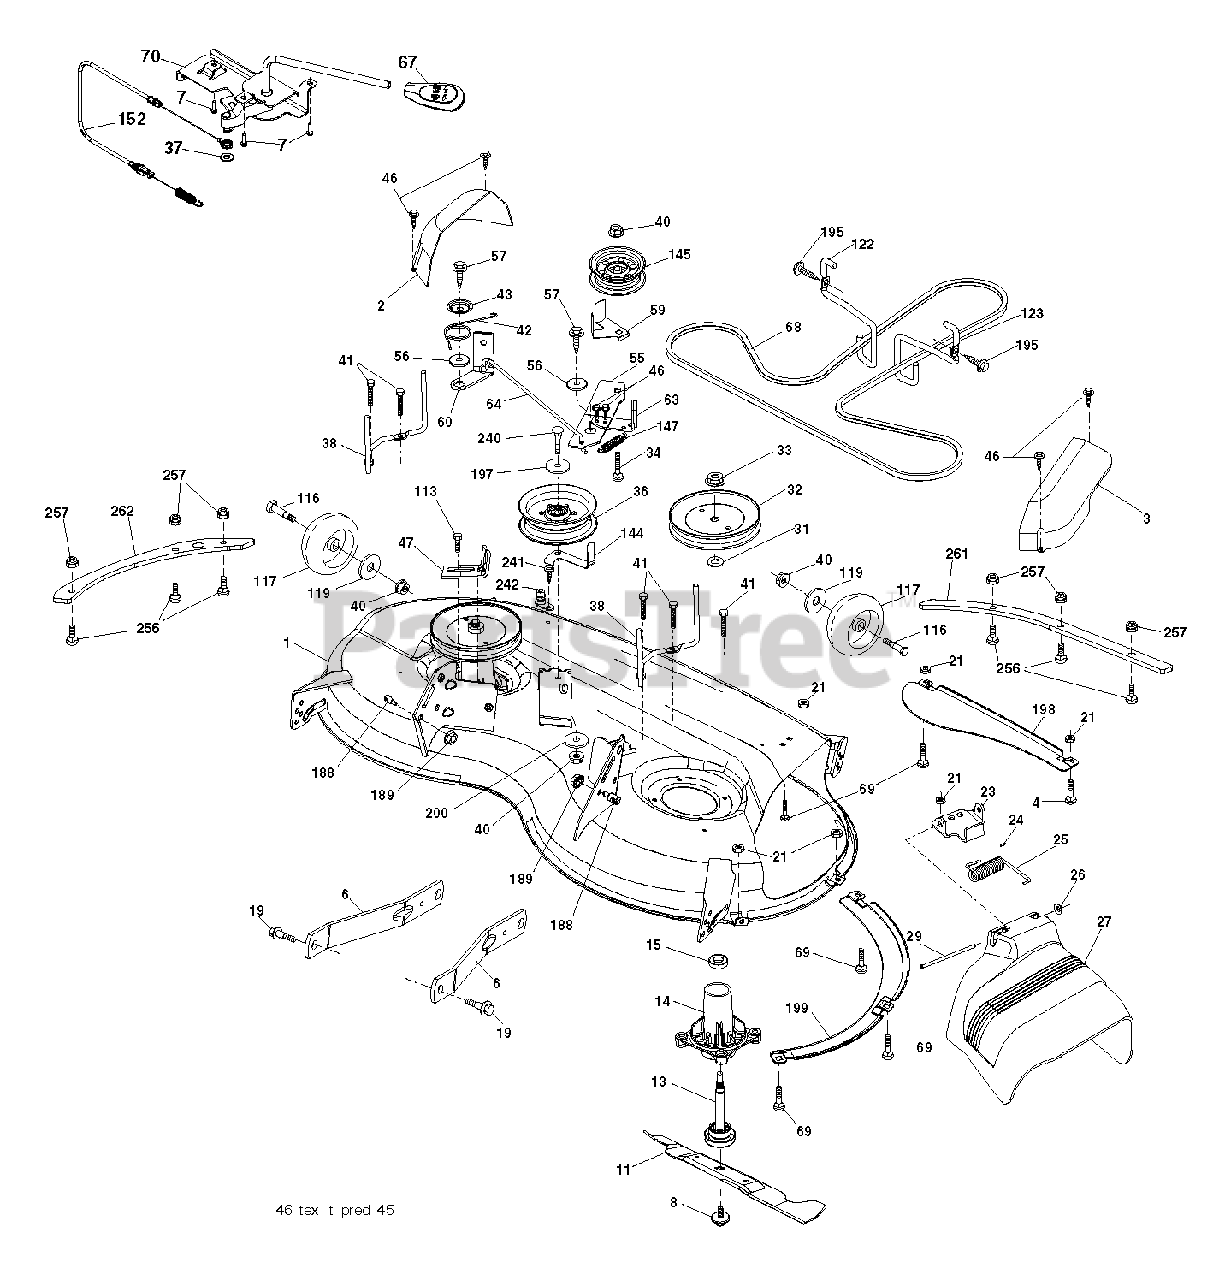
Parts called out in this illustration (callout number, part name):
1	DECK SVC 46"583900906X421
2	COVER.MANDREL.LH.46"
3	COVER.MANDREL.RH.46"
4	BOLT
6	ARM.SUSPENSION.MOWER.R
7	SCREW.#10 X 0.750.BOS (2 2)
8	BOLT.WASHER.ASM.7/16-2
11	BLADE.MOWER.46".HI.LIFT
13	SHAFT.ASM.MDRL.N/GREASE.38
14	HOUSING.MANDREL.4PT.
19	BOLT.SHOULDER
21	LOCKNUT
23	BRKT.DEFLECTOR.38"2005+
24	CAP-SLEEVE LT
25	SPRING.TORSION.DEFLECT
26	NUT PUSH M
27	SHIELD.DEFLECTOR.MOWER.46"BLAC
29	ROD.HINGE
31	WASHER.SPACER.MANDREL
32	PULLEY.MANDREL.5.438.PD
33	NUT.FLANGE.LOCK.TOP
34	BOLT.3/8-16X1.50
36	PULLEY.IDLER.2006
38	KEEPER.BELT.MANDREL.PULLEY
40	NUT LOCK FLG 3/8-16 UNC
41	Hex Washer Head Bolt, .313-18 X 1.19
42	SPRING.TORSION.BRAKE
43	SRPING.TORSION.RETAINE
46	SCREW.1/4-20X5/8
47	BRKT.CLUTCH.CABLE
55	IDLER.ARM
56	SPACER.RETAINER
57	SCREW 3/8-16X1
59	GUARD, BELT
60	ARM BRAKE MOWER RH 38"
64	LINKAGE BRAKE
67	HANDLE.CLUTCH.CABLE.LT
68	V-BELT
69	BOLT
70	CLUTCH.ASM.MANUAL.YT.PREDATORQ
113	BOLT.5/16HEX.WHS.HD
116	BOLT M
117	WHEEL.GAGE.HALF.SPOKED
119	WASHER
122	KEEPER BELT ENGINE LH
123	KEEPER BELT RH
144	KEEPER.BELT.MOWER
145	PULLEY.IDLER.48"PRIMARY
147	SPRING RETURN
152	CABLE.MECHANICAL.CLUTCH
188	STUD.FASTNER.W/ANTI-ROTATE
189	NUT LOCK HEX FLANGE 5/16-18
195	SCREW, 3/8-16X3/4
197	WASHER
198	BAFFLE CENTER FRONT
199	BAFFLE FRONT RH
200	WASHER.13/32 X 1 X 1/2.11GUARD
240	BOLT-HEX EAK
241	SCREW.TT.#10-32X.5.3/8.FLANGE
242	PORT.WASHOUT
256	Buttonhead Screw, 5/16-18
257	NUT T
261	Deck Reinforcement Plate, 46 F
262	Side Reinforcement Plate, 46" Bolt-on
